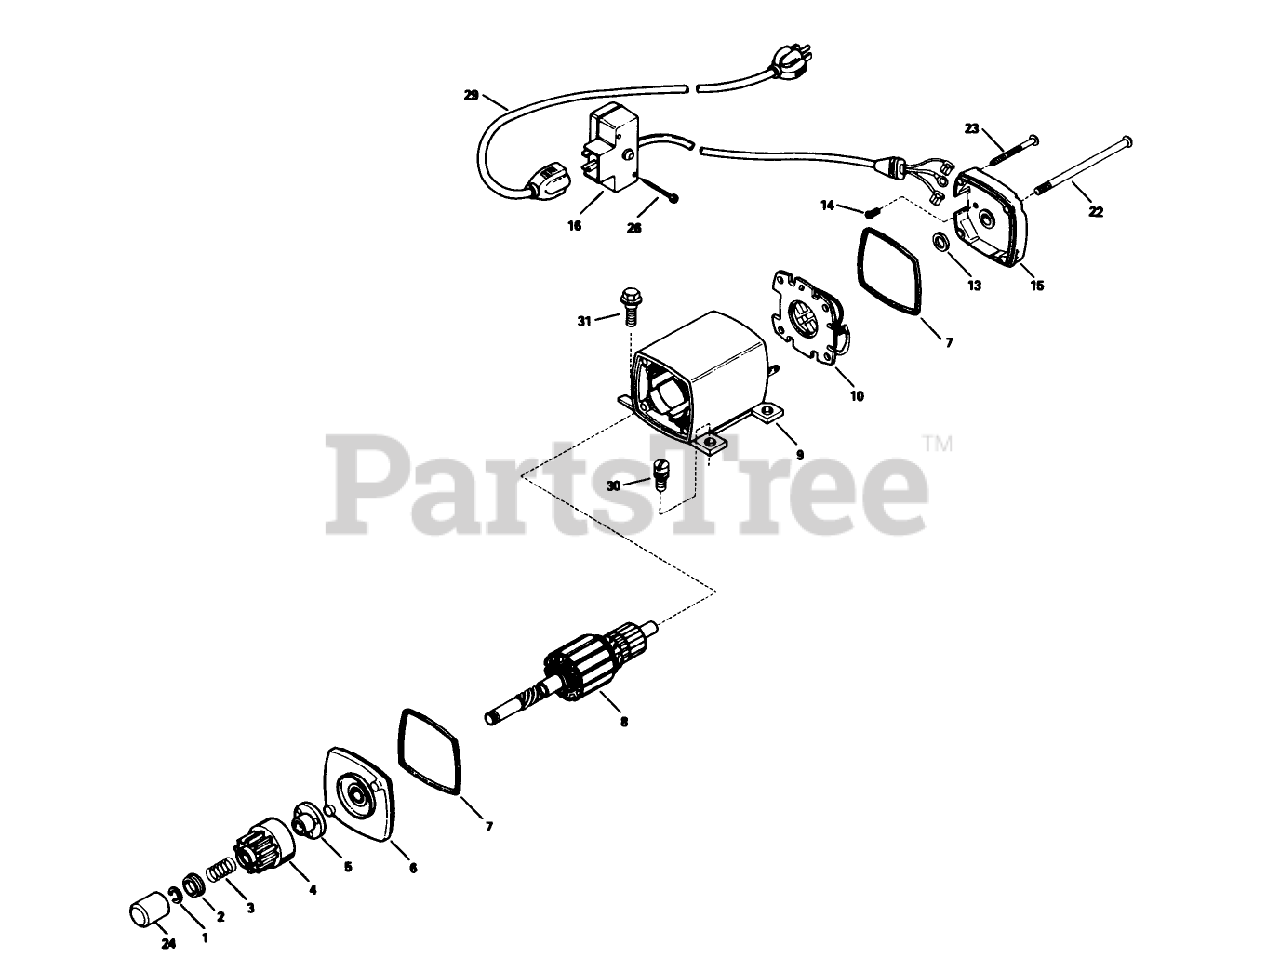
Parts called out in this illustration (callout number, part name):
1	Ring-Retainer
2	Retainer-Spring
3	Spring-Anti Drift
4	Gear
5	Nut-Engaging
6	Cap Assembly-Cap End (Incl. Ref. #7)
7	O-Ring
8	Armature
9	Housing Assy.
10	Card ASM
13	Washer-Thrust
14	Screw-Ground
15	Cap Assembly (Incl. Ref. #7)
16	Box Assembly-Switch (Incl. Ref. #26)
22	Bolt-Case
23	Screw-Ground
24	Cover-Dust
26	Screw
29	Cord-Extension
30	Screw
31	Screw (1/4-20x1/2)
